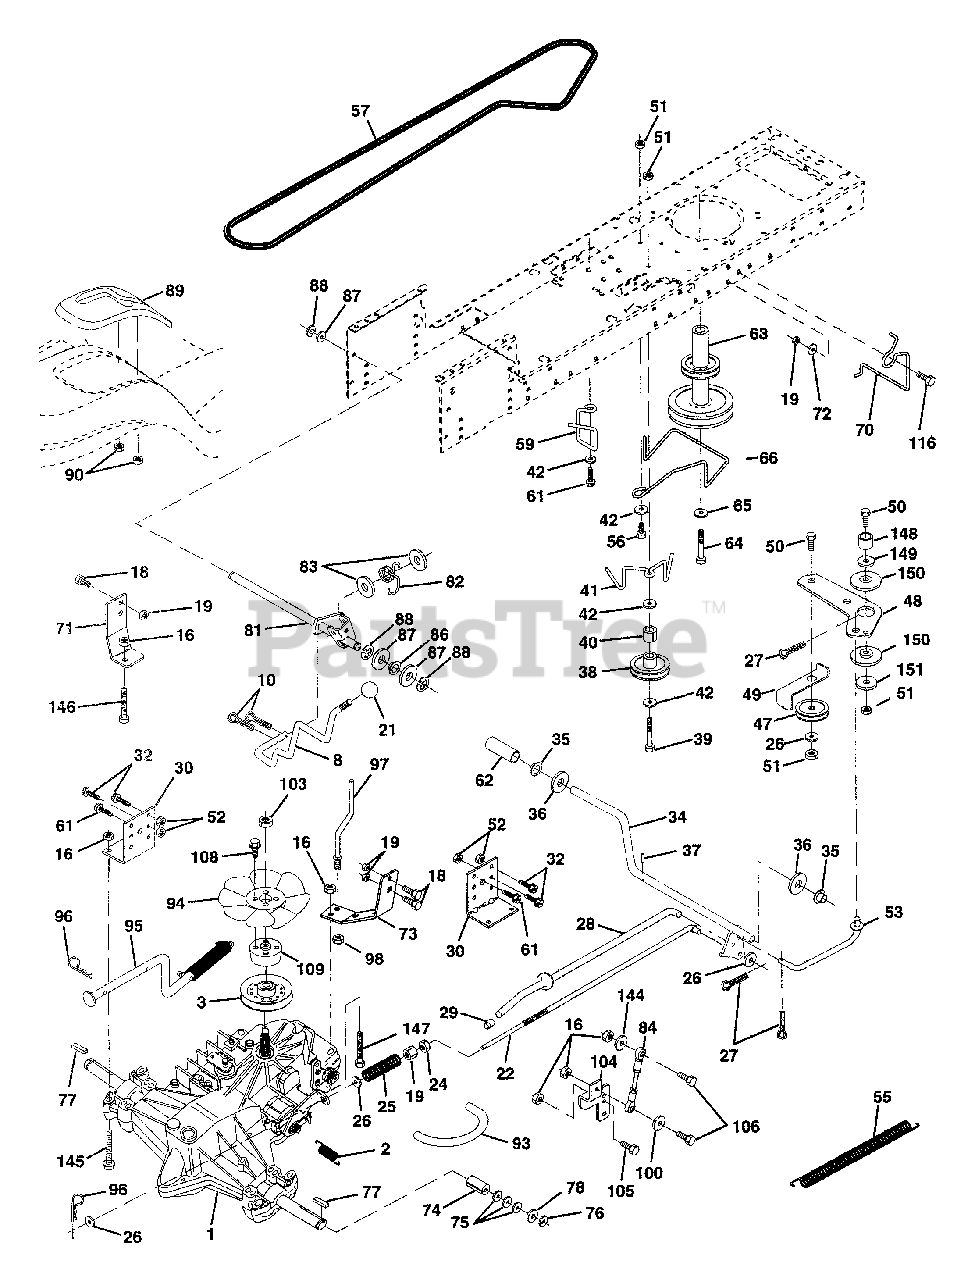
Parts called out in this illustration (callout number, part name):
1	Transaxle Assembly
2	Spring, Return, Brake
3	Pulley, Transaxle
8	Rod Shift Fender STLT
10	Pin Cotter 1/8 x 1 CAD
15	Bolt Hex Flghd 5/16-18 Gr 5
16	Nut Lock Hex W/Ins 5/16-18 Unc P
18	Bolt Fin Hex 3/8-16 Unc x 1 Gr. 5
19	Nut Lock Hex W/Wsh 3/8-16 Unc
21	Knob 1/2-13
22	Rod, Brake Hydro
24	Nut
25	Spring, Brake Rod
26	Washer
27	Pin Cotter 1/8 x 3/4 CAD.
28	Rod, Parking Brake
29	Cap, Parking Brake
30	Bracket, Transaxle
32	Bolt Hex Hd 5/16-18 Unc x 3/4
34	Shaft, Foot Pedal
35	Bearing, Nylon
37	Pin, Roll
38	Pulley, Idler, Flat
40	Spacer, Split
41	Keeper, Belt Retainer
42	Washer 13/32 x 13/16 x 12 Gauge
47	Pulley, Idler, V-Groove
48	Bellcrank Clutch Grnd Drv STL
49	Retainer, Belt
50	Bolt
51	Nut Crownlock 3/8-16
52	Nut Crownlock 5/16-18
53	Link, Clutch
55	Spring, Return, Clutch
56	Bolt Fin Hex 3/8-16 Unc x 1-1/4
57	V-Belt, Ground Drive
59	Keeper, Center Span
61	Screw Thdrol. 3/8-16 x 3/4 Ty. TT
62	Cover, Pedal
63	Pulley, Engine Mech 38" Deg Hydro
64	Bolt, Hex
65	Washer
66	Keeper, Belt Engine Hydro
70	Keeper Belt Engine
71	Strap Torque Lh Hydro 500 18"
72	Washer 13/32 x 1-1/4 x 12 Gauge
73	Strap Torque Rh Hydro 500 18"
74	Spacer, Split
75	Washer 25/32 x 1-1/4 x 16 Gauge
77	Key, Square
78	Washer 25/32 x 1-5/8 x 16 Gauge
81	Shaft Asm. Cross Hydro 500/18" 98
82	Spring Torsion T/A
83	Washer 17/32 x 3/4 x 16 Ga.
84	Rod, Tie Hydro Sph Ball 500
87	Washer 21/32 x 1-1/4 x 16 Ga.
88	Ring Klip #5304-62
89	Console, Shift Hydro STLT
90	Nut Self-Thd Wsh-Hd 1/4 Zinc
93	Line Fuel Hydro 4"
94	Fan, Hydro 7"
95	Control Asm. Bypass Hydro
96	Retainer Spring 1" Zinc/Cad
97	Keeper Belt Rh Hydro 500
98	Nut Keps Hex 3/8-16 Unc
100	Washer 11/32 x 3/4 x 16 Ga.
103	Nut, Hex Jam Toplock 1/2-20 Unf
104	Arm, Control Pump
105	Screw Cap Hex 5/16 x 18 x 1
106	Bolt Fin Hex 5/16-18 Unc x 1-1/4
108	Screw Hex Wh Hd #10-24 x 1-5/8
109	Adaptor Fan/Hydro Lt Hyd Alum
116	Bolt, RDHD SQ Neck 3/8-16 x 1.25
144	Washer 11/32 x 5/8 x 16 Ga.
146	Bolt Hex FIg Hd 5/16-18 x 2-1/4
147	Bolt Hex FIg Hd 5/16-18 x 1-1/2
149	Spacer Retainer PM Mower
150	Bushing Nylon Collered
151	Washer 13/32 x 2 x 10 Ga.
